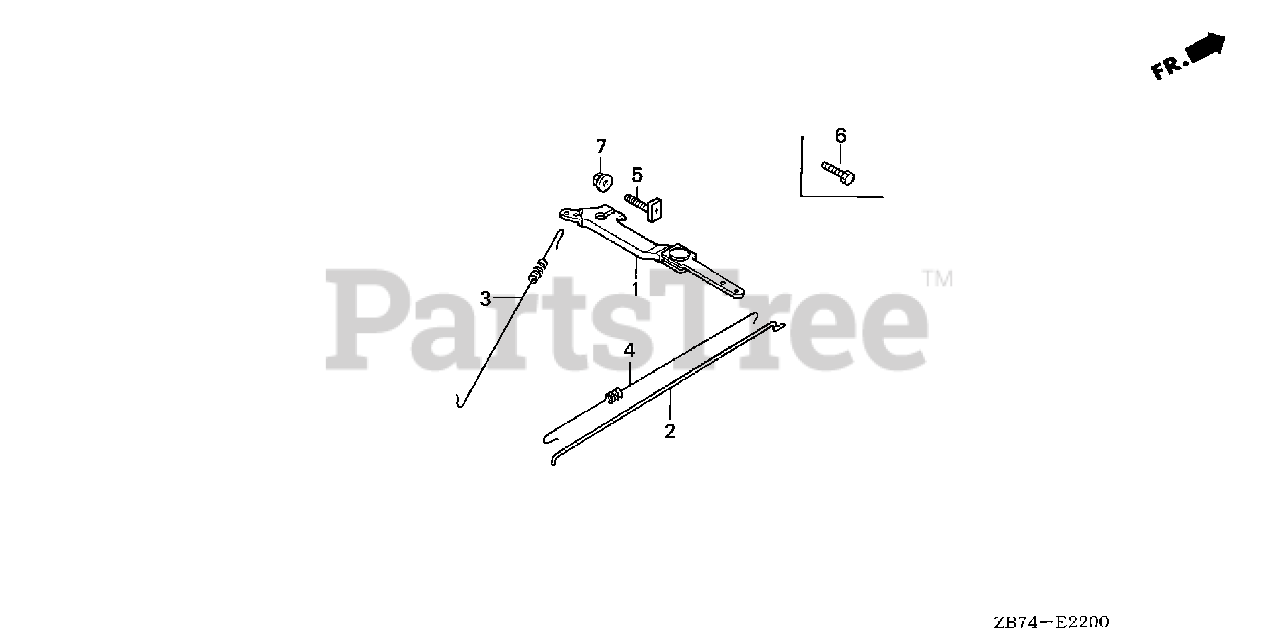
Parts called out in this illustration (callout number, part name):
1	ARM, GOVERNOR
2	ROD, GOVERNOR
3	SPRING, GOVERNOR (L=145.0MM) (WIRE DIAMETER 1.0MM)
4	SPRING, THROTTLE RETURN
5	BOLT, GOVERNOR ARM
7	NUT, FLANGE (6MM)
